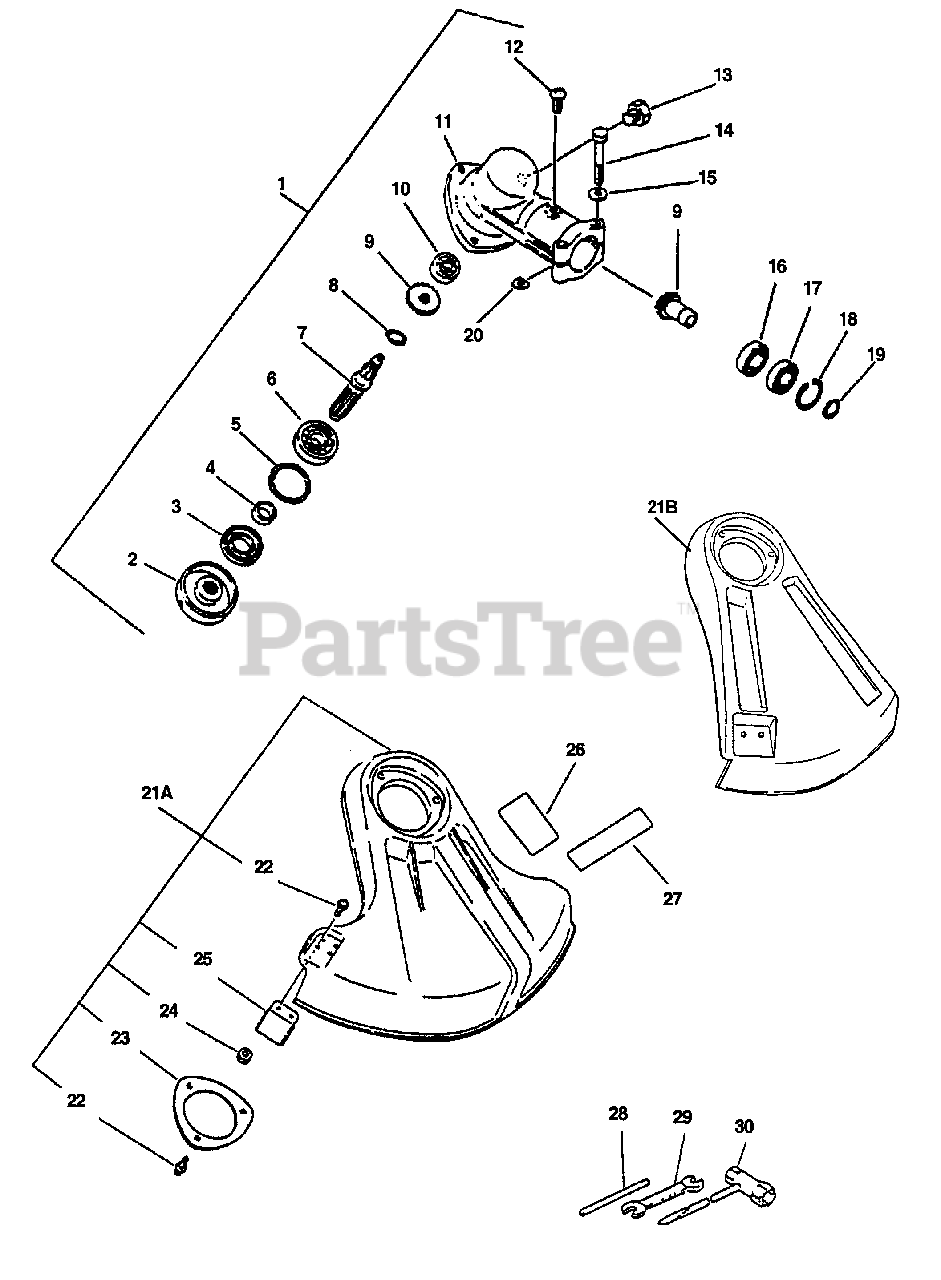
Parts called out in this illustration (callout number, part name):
1	GEAR CASE ASSY
2	PLATE, ADAPTOR - UPPER
3	SEAL, OIL 22
4	SPACER 11.8×15×9
5	RING, SNAP Ø32
6	BEARING, BALL 6201
7	SHAFT, GEAR
8	RING, SNAP Ø10
9	GEAR SET
10	BEARING, BALL 609
11	HOUSING, GEAR CASE
12	SCREW 5×10
13	BOLT 8×8 SP
14	BOLT 5×35 SP
15	WASHER, FLAT 5.5×10×0.8
16	BEARING, BALL 6900
17	BEARING, BALL 6900Z
18	RING, SNAP Ø22
19	RING, SNAP Ø12
21A	DEBRIS SHIELD KIT
21B	DEBRIS SHIELD KIT
22	SCREW 5×16
23	BRACKET, SHIELD
24	NUT M5
25	CUTTER, LINE
26	LABEL, CAUTION
27	LABEL, ECHO
28	TOOL, LOCKING 5×120 MM
29	SPANNER 8×10
30	T-WRENCH
